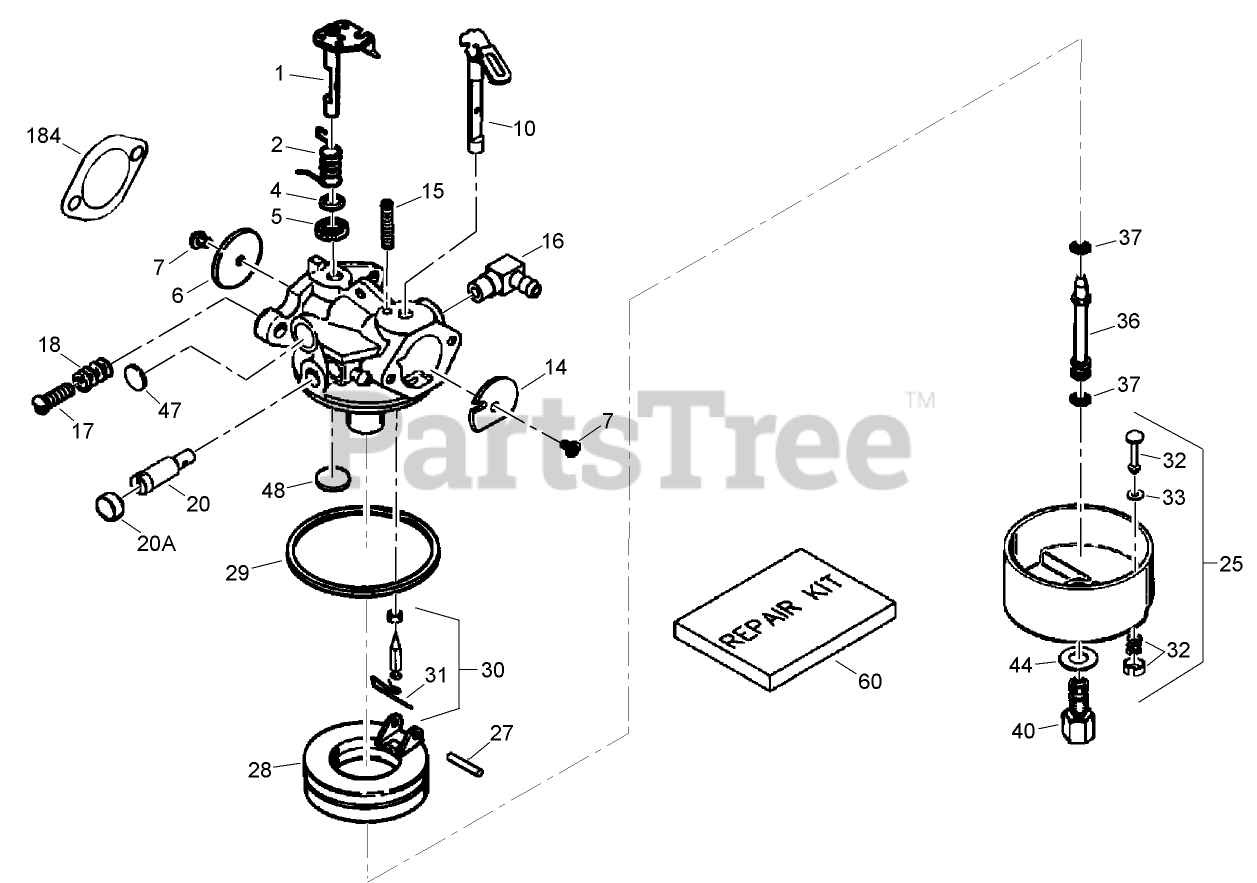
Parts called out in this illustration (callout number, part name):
1	Throttle Shaft and Lever ASM
2	Spring-Return, Throttle
4	Washer-Seal, Dust
5	Seal-Dust
6	Shutter-Throttle
7	Screw-Shutter
10	Choke Shaft and Lever ASM
14	Shutter-Choke
15	Spring-Positioning, Choke
16	Fitting-Fuel
17	Screw-Throttle Crack and Idle Speed
18	Spring-Tension
20	Screw-Restrictor, Idle
20A	Cap-Screw, Idle Restrictor
25	Float Bowl Asm. (Incl. Ref. # 32, 33)
25	Bowl-Float (no drain)
27	Shaft-Float
28	Float (Plastic)
29	O Ring-Bowl, Float
30	Inlet Needle, Seat Clip Assy. (Incl. No. 13)
31	Clip-Spring
32	Bowl Drain ASM
33	Gasket-Plunger, Drain
36	Tube-Nozzle, Main
37	O-Ring
40	Nut-Bowl, High Speed
44	Washer-Nut, Bowl
47	Plug-Welch, Idle Mixture Well
48	Plug-Welch, Atmospheric Vent
60	Repair Kit
184	Gasket
